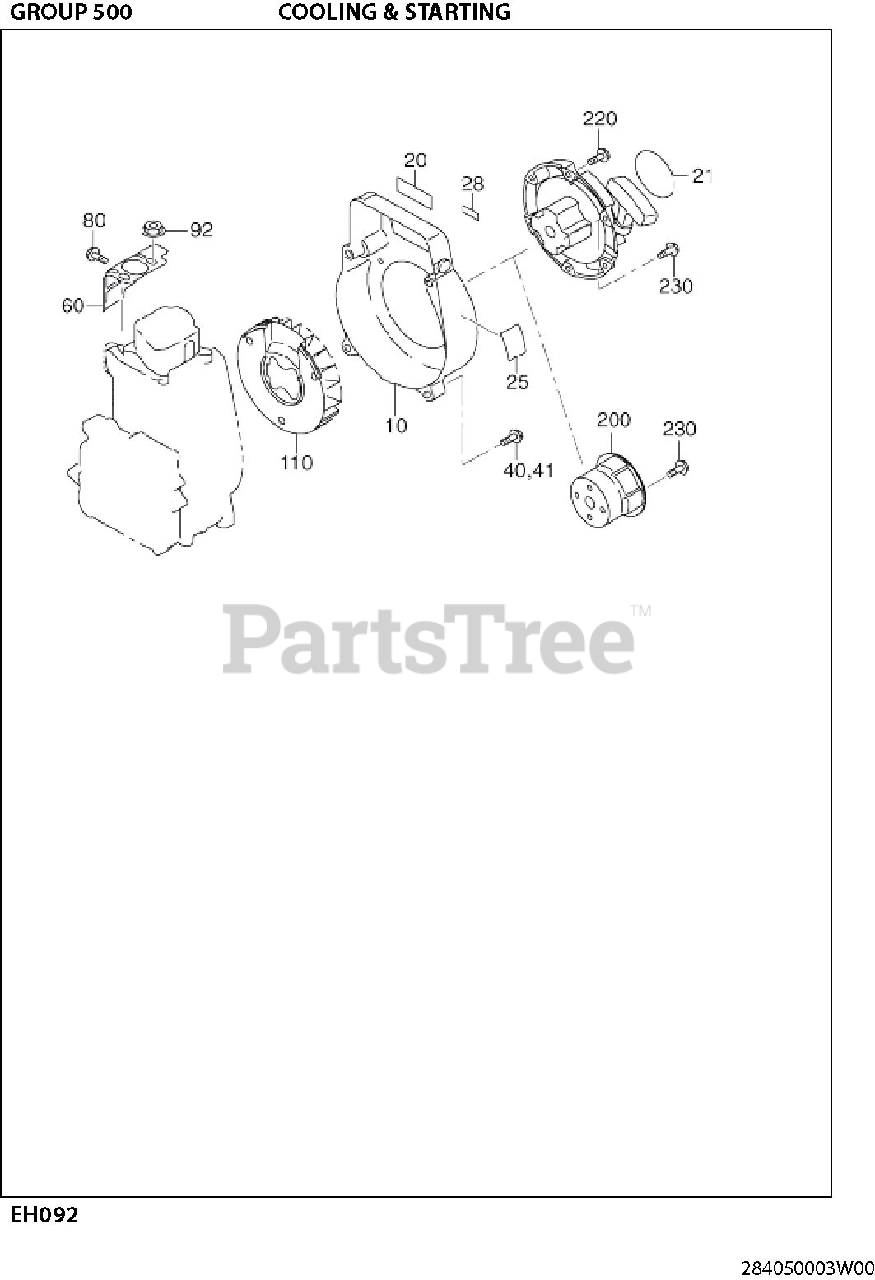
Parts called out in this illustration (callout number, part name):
10	BLOWER HOUSING CP
60	CYLINDER BAFFLE CP
110	COOLING BLOWER
